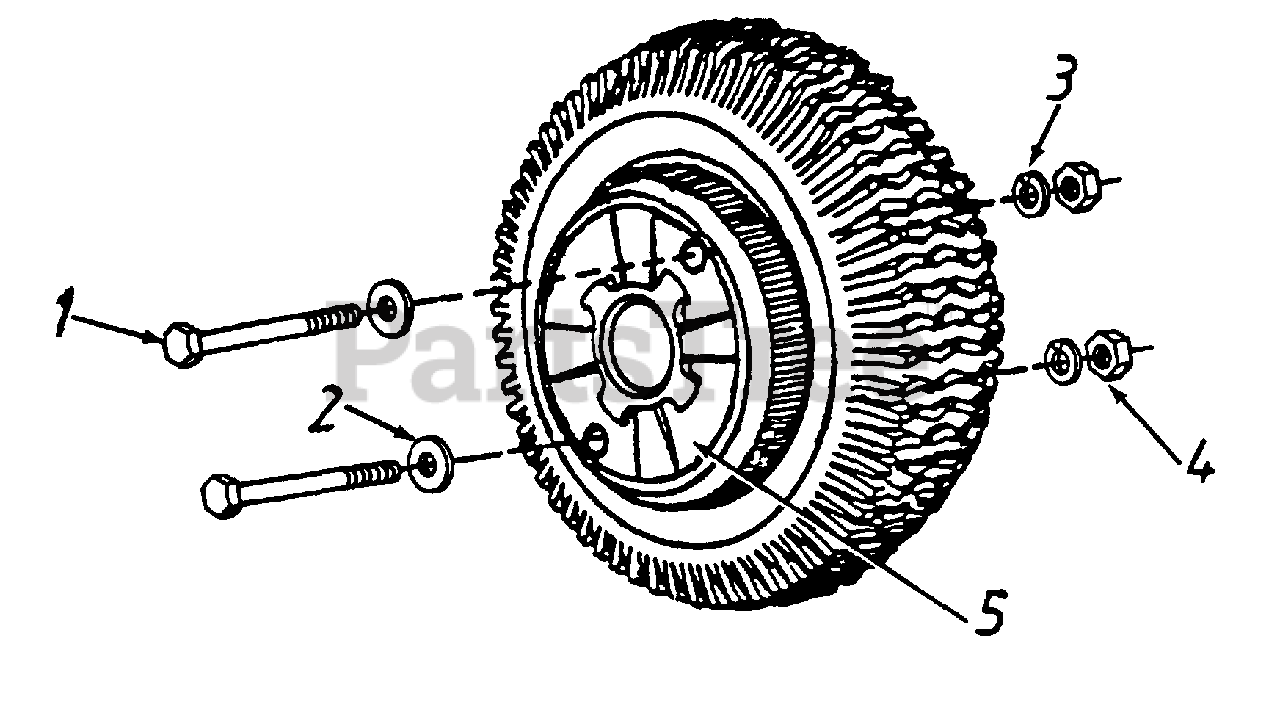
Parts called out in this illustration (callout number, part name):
1	Hex Bolt 3/8-16 x 7-1/2" Lg.
2	Fl-Wash. 3/8" I.D.
3	L-Wash. 3/8" I.D.
4	Hex Nut 3/8-16 Thread
5	31 lb. Wheel Weights
